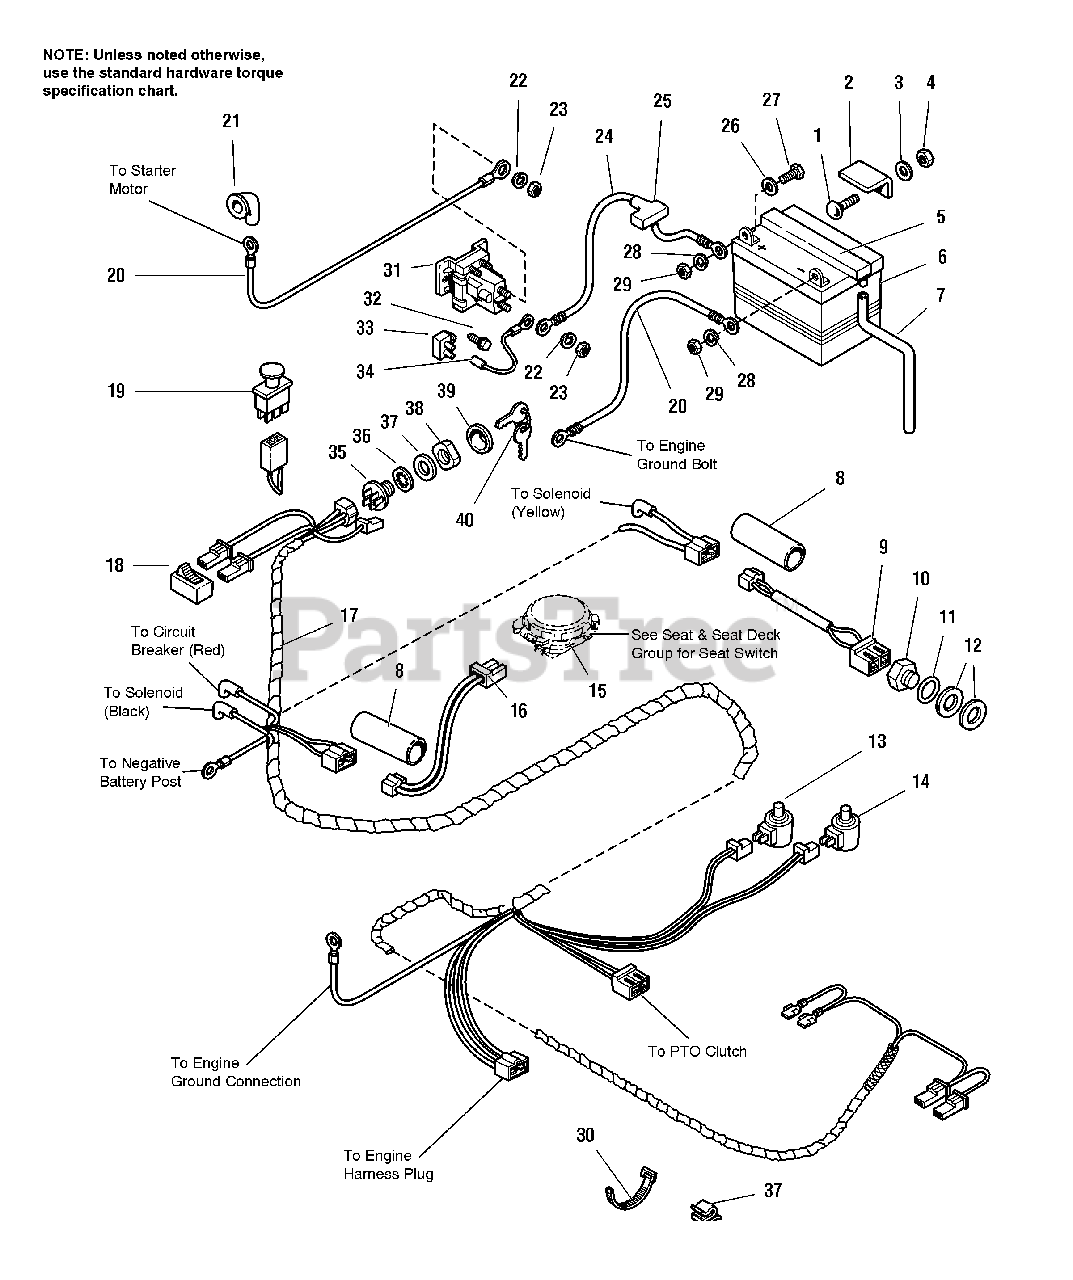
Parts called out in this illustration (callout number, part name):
1	CARRIAGE BOLT, 5/16-18 x 3/4
2	CLAMP, Battery
3	WASHER, Plain, 5/16
4	NUT, Hex Nylon Lock, 5/16-18
5	CAP, Vent, Battery
7	HOSE, Drain
8	TUBE, Shrink
9	WIRE ASSEMBLY, Transmission
10	SWITCH, Transmission
11	SEAL, O-Ring
12	WASHER, 5/8
13	SWITCH, Pedal, N.C., Gray
14	SWITCH, Pedal, N.O., Black
15	KEY, Ignition
16	WIRE ASSEMBLY, Seat Switch
17	WIRING HARNESS, Main
18	SWITCH, Headlights
19	SWITCH, PTO
20	CABLE, (Solenoid to Starter & Battery to Ground)
21	COVER, Terminal
22	LOCKWASHER, 5/16
23	NUT, Hex, 5/16-24 NF
24	CABLE, Battery, Positive
25	BOOT, Insulator
26	WASHER, 1/4
27	CAPSCREW, Hex Hd., 1/4-20 x 3/4
28	LOCKWASHER, 1/4
29	NUT, Hex, 1/4-20
31	SOLENOID
32	CAPSCREW, Taptite Hex Washer Hd, 1/4-20 x 5/8
33	CIRCUIT BREAKER
34	WIRE ASSEMBLY
35	SWITCH, Ignition, 6-Pole
36	LOCKWASHER, Internal Tooth, 5/8
37	CLIP, Wire
38	NUT, Hex, Flange, 5/8-32
39	COVER, Ignition
40	KEY, Ignition
